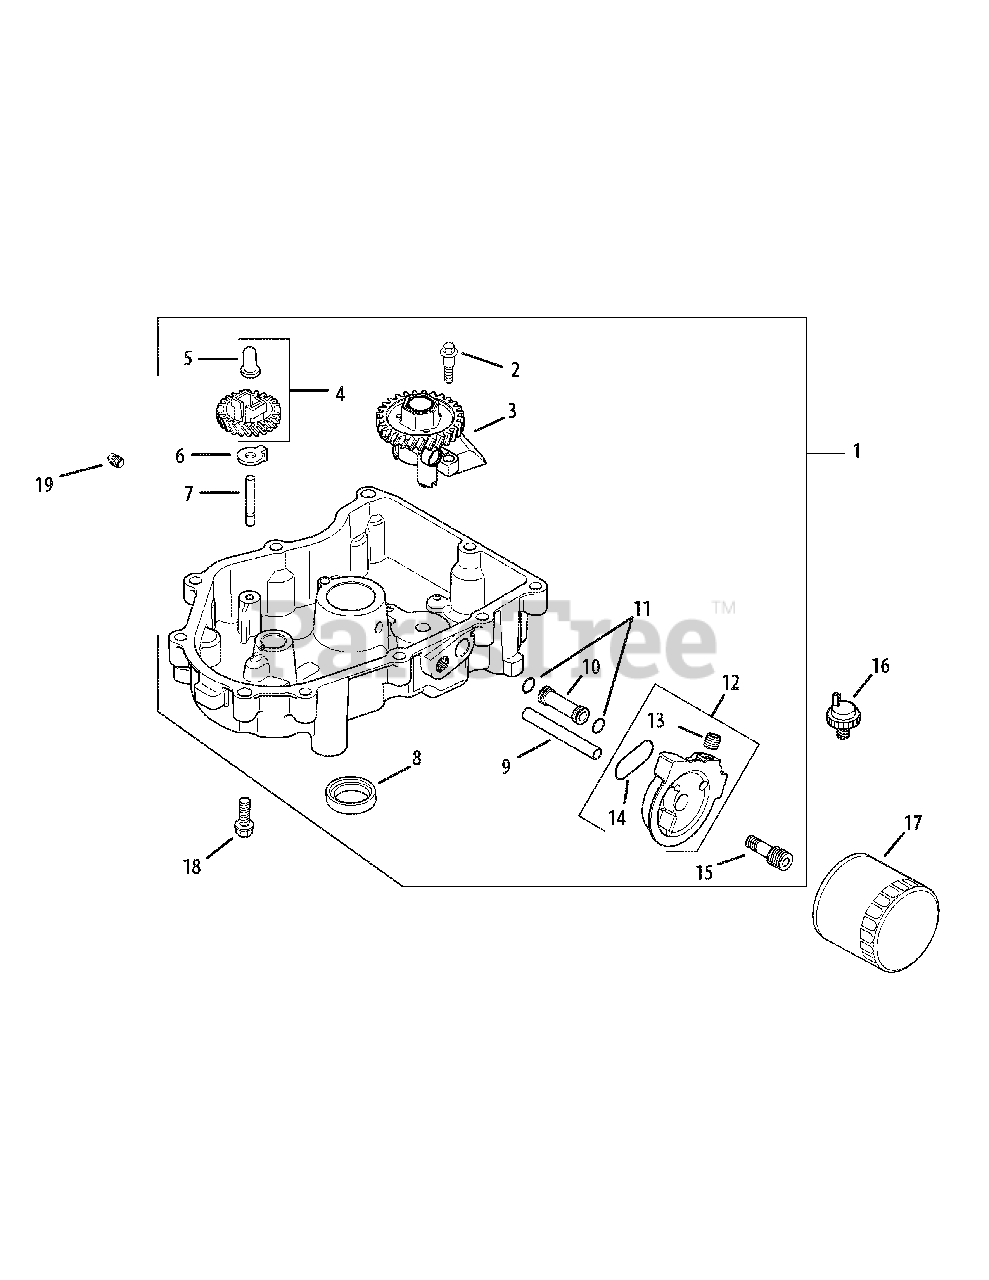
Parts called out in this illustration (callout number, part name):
1	Pan assembly, oil
2	Screw, hex. flange thread forming shoulder
3	Oil pump assembly
4	Kit, governor gear w/pin
5	Pin, governor regulating
7	Shaft, governor gear
8	Seal, oil (PTO end)
9	Tube, oil feed - filter to oil pan
10	Tube, oil feed - oil pan to lter
12	Adapter, oil filter
13	Plug, hex. ctsk. 1/8"
14	O-Ring, oil lter adapter
15	Nipple, oil lter
16	Switch, pressure
18	Screw, hex. flange M8x1.25x45
19	Plug, sq. hd. solid 3/8"
